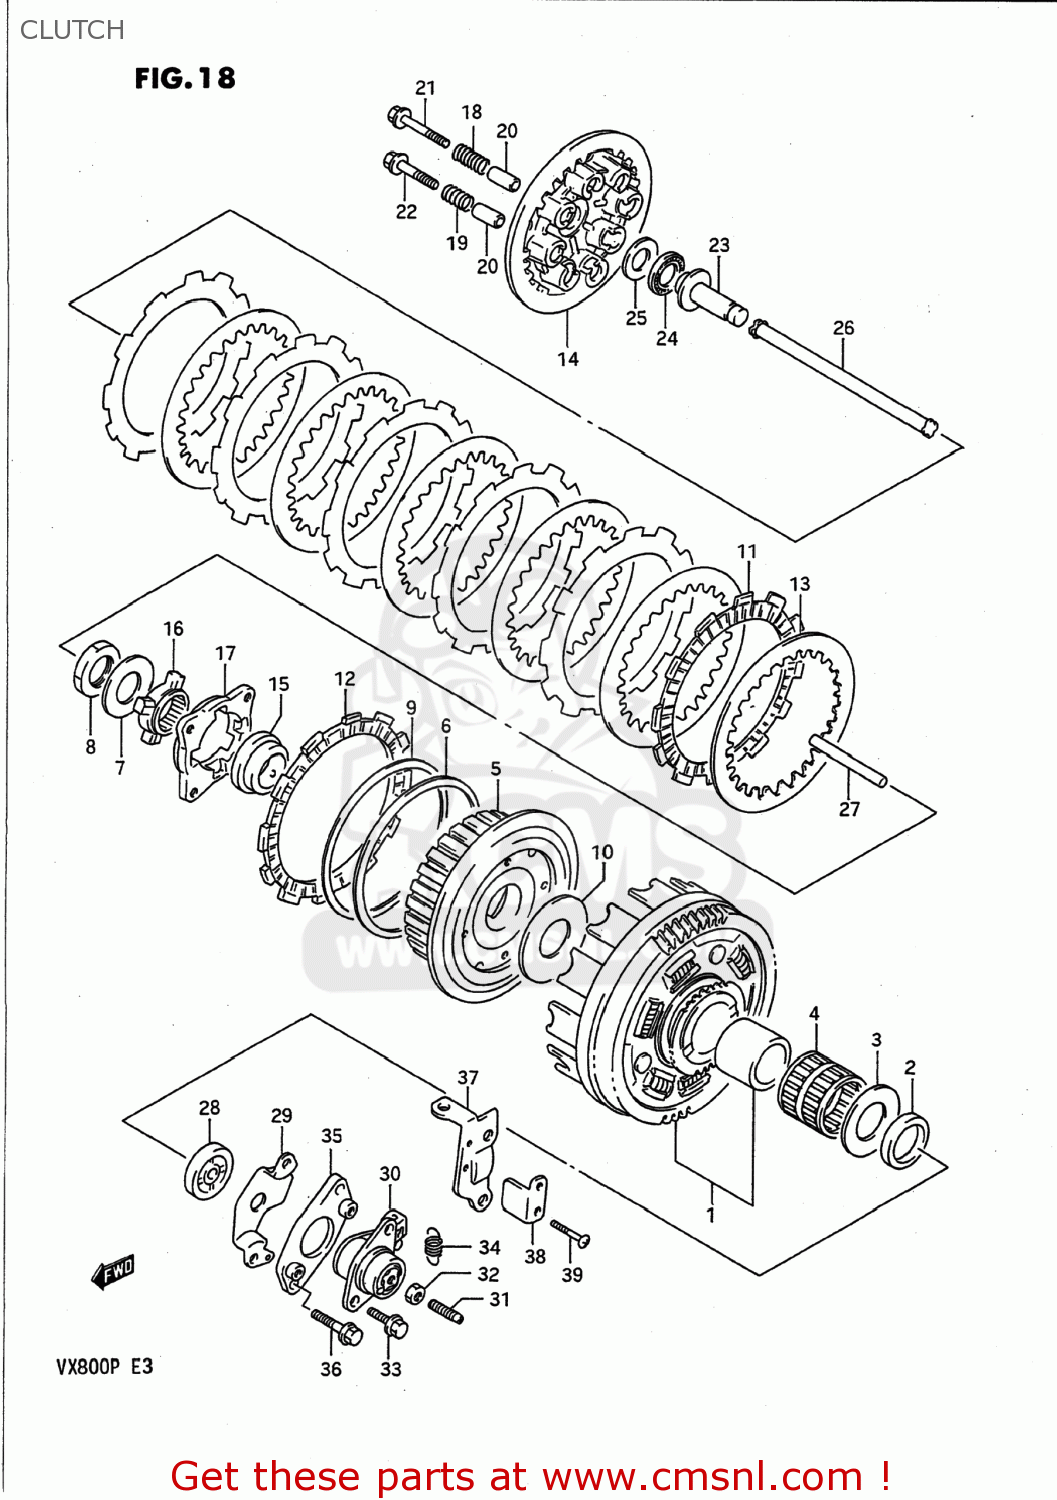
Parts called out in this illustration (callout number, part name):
1	GEAR ASSY,PRI DRIVEN(NT:71)
2	SPACER(25X38X6.5)
3	WASHER(25X50X2.5)
4	BEARING(35X40X35.8)
5	HUB,CLUTCH SLEEVE
6	SEAT,WAVE WASHER(T:1.4)
7	WASHER
8	NUT
9	WASHER
10	WASHER(25X60X2.5)
11	PLATE,CLUTCH DRIVE (NAS)
12	PLATE,CLUTCH DRIVE(T:3.5) (NAS)
13	PLATE,CLUTCH DRIVEN(T:1.6) (NAS)
14	DISC,CLUTCH PRESSURE
15	SPACER,CLUTCH SLEEVE HUB
16	CAM,CLUTCH NO.1
17	CAM,CLUTCH NO.2
18	SPRING
19	SPRING
20	SPACER (6,1X9X24.1)
21	BOLT(6X40)
22	BOLT(6X32.5)
23	PIECE,CLUTCH PUSH
24	BEARING(15X28X2)
25	WASHER
26	ROD,CLUTCH
27	ROD,CLUTCH PUSH,L
28	SEAL,OIL(6X34X11)
29	RETAINER,CL PUSH ROD OIL SEAL
30	SCREW ASSY,CLUTCH RELEASE
31	SCREW(6X25)
32	NUT 6MM
33	BOLT
34	SPRING
35	PLATE,CLUTCH RELEASE SCREW
36	BOLT
37	GUIDE,CLUTCH CABLE
38	PLATE,CLUTCH CABLE GUIDE
39	SCREW (5X8)
